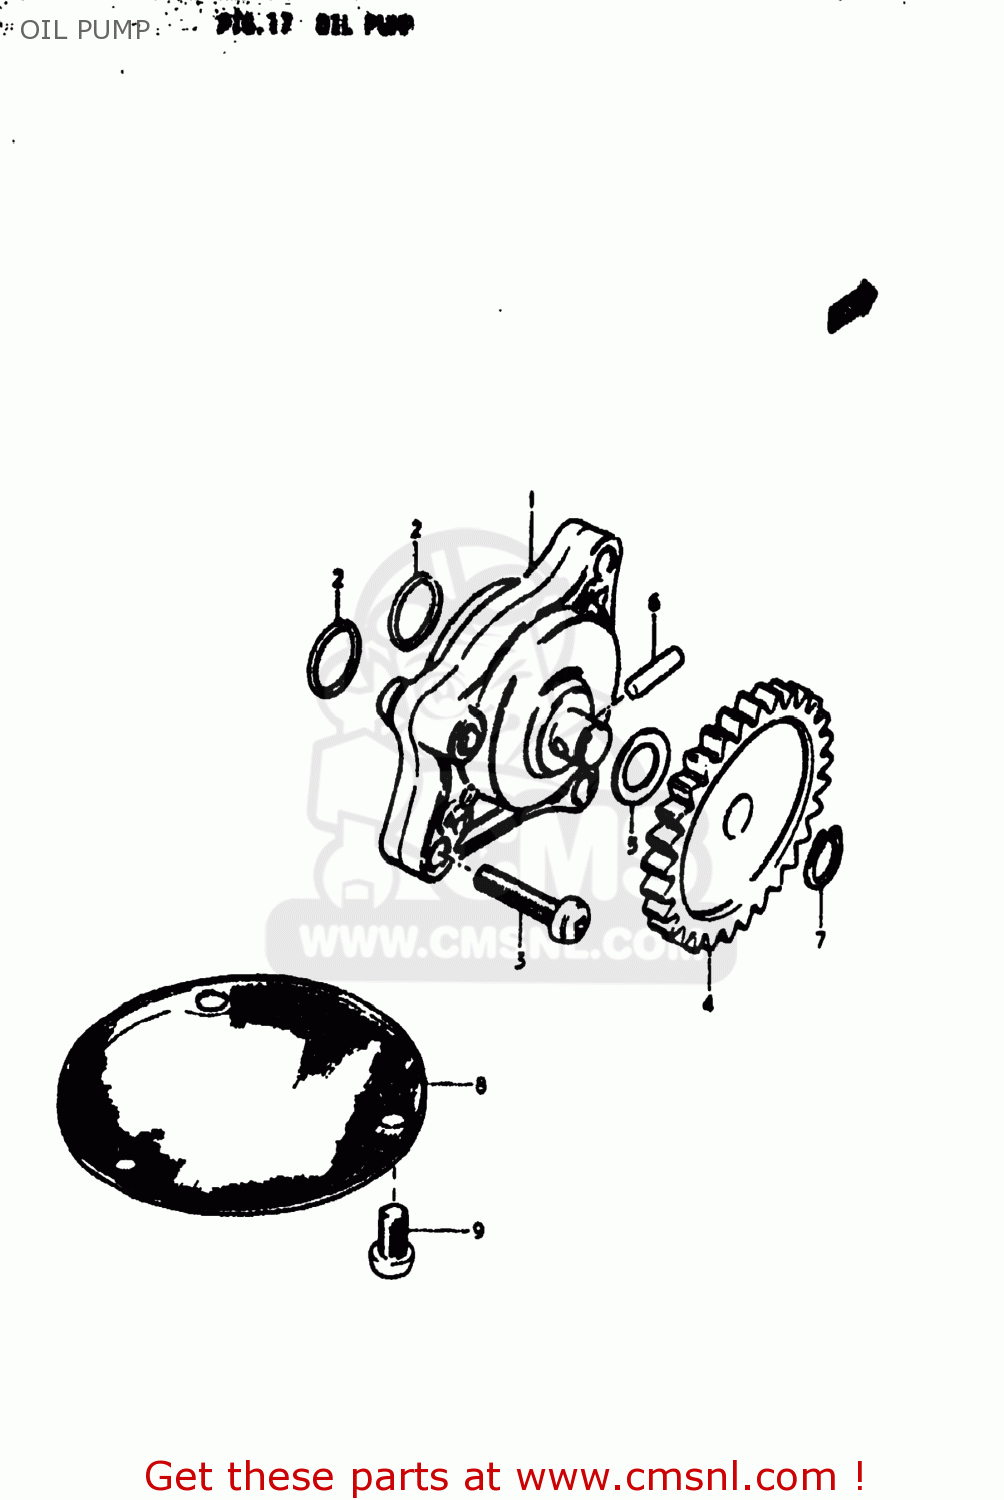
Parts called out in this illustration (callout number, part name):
1	PUMP ASSEMBLY,OIL
2	O RING(D:1.9,ID:13)
3	SCREW
4	GEAR,ENG OIL PUMP DRIVEN
5	SHIM
6	PIN(4X15.8)
7	CIRCLIP
8	STRAINER,ENGINE OIL
9	SCREW 6X12
